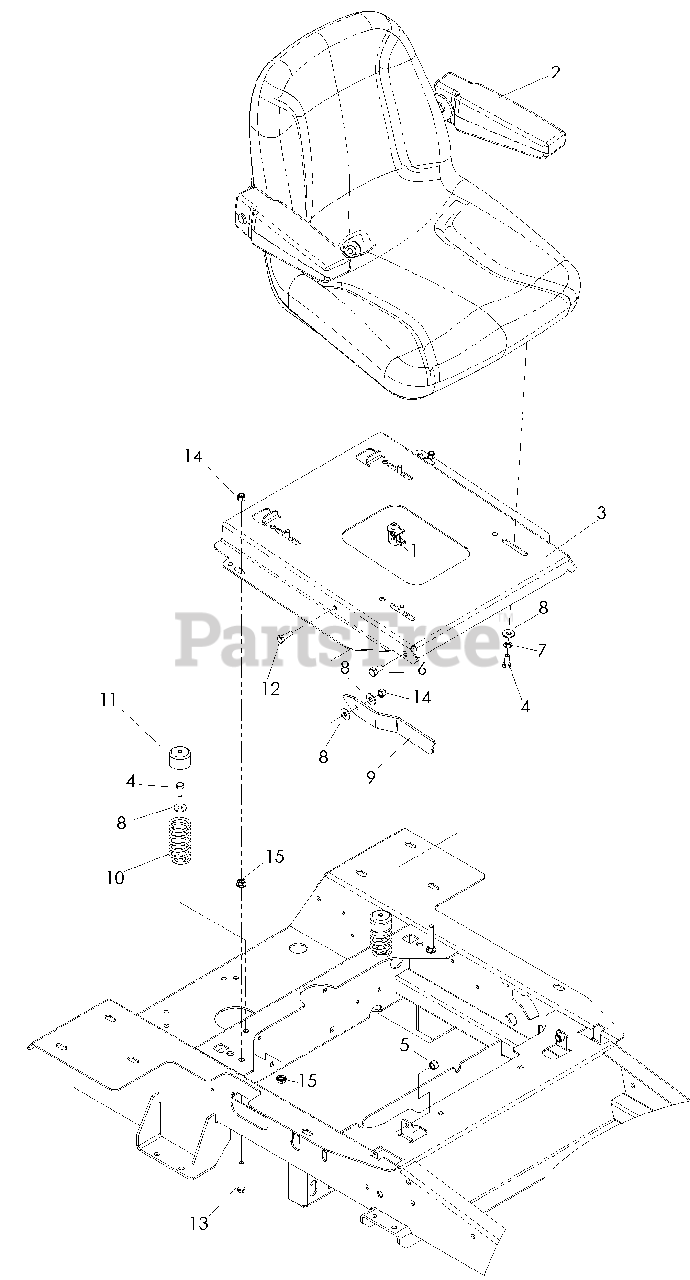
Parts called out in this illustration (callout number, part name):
1	SEAT SWITCH
2	SEAT W/ARMREST
4	HCS 5/16-18 x 3/4
5	NUT 3/8-16 NYLOC
6	HCS 3/8-16 x 3/4
7	LOCKWASHER 5/16
8	WASHER 5/16
9	ARM, PROP, SEAT
10	SEAT SPRING
11	SPRING CAP
12	HCS 5/16-18 x 1
13	HCS 5/16-18 x 2 1/4 TAP
14	NUT 5/16-18 NYLOC
15	NUT 5/16-18 WHIZLK
